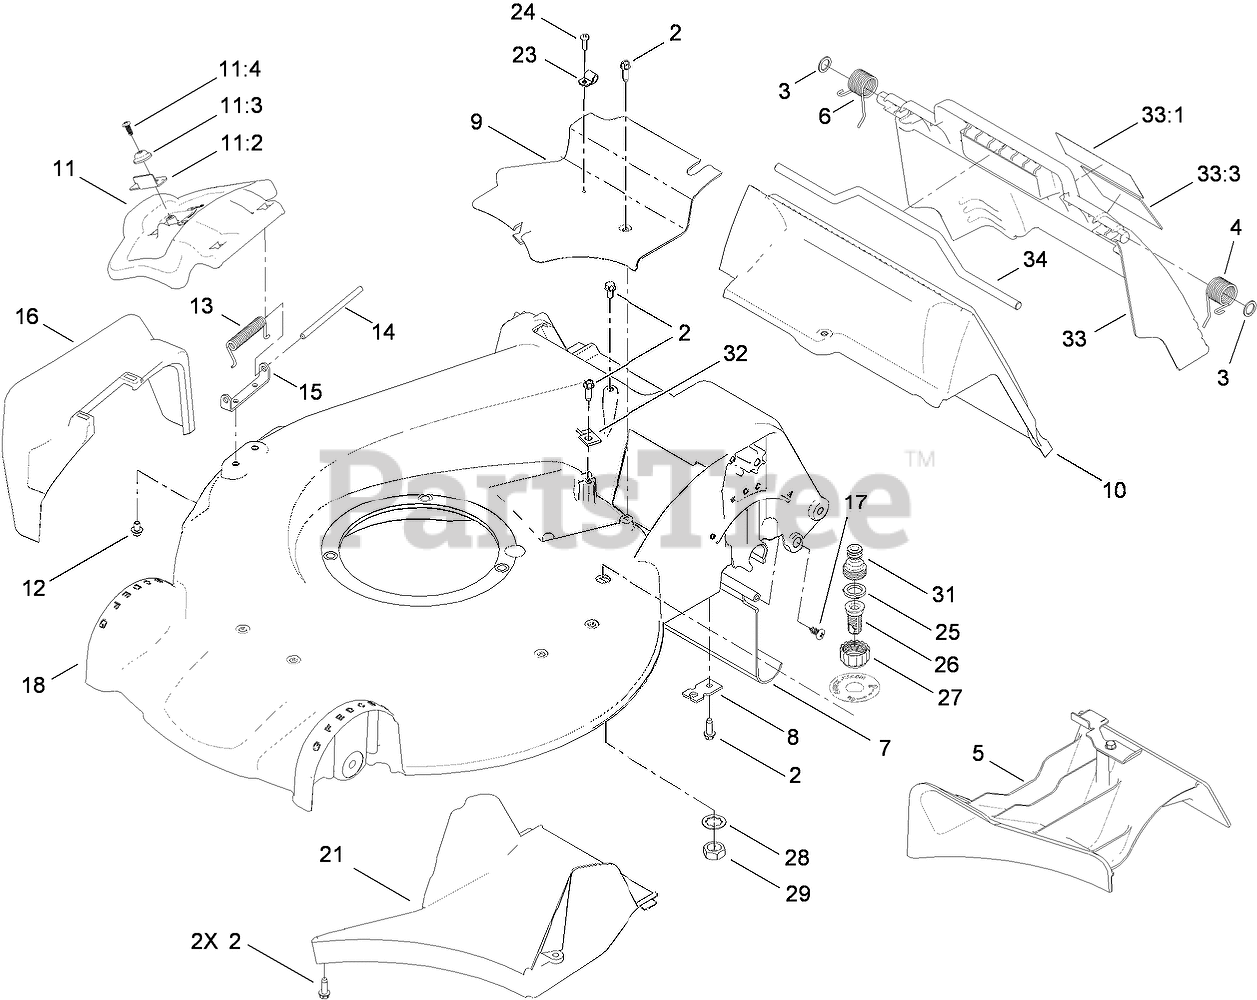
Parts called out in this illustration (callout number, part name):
2	SCREW-HWHTF
3	WASHER-NYLON
4	SPRING-TORSION
5	MULCH PLUG ASM
6	SPRING-TORSION
7	SHIELD-TRAILING
8	BRACKET-CABLE, TRACTION
9	COVER-BELT
11	DISCHARGE DOOR ASM
11:2	LATCH-DOOR
11:3	CAP-DOOR
11:4	SCREW-PLASTITE
12	SCREW-HWH
13	SPRING-TORSION
14	ROD-COVER
15	BRACKET-COVER
16	CHUTE-DISCHARGE, SIDE
17	SCREW-PTH
18	HOUSING ASM
21	TUNNEL-DISCHARGE
23	CLAMP
25	WASHER-SEAL, WASHOUT PORT
26	PORT-WASHOUT
27	COUPLING-HOSE, WASHOUT PORT
28	WASHER-TOOTH, INTERNAL
29	NUT-JAM
31	ADAPTER-CONNECT, QUICK
32	CLAMP-CABLE
33	REAR DOOR ASM
33:1	DECAL-WARNING
33:3	DECAL-WARNING
34	ROD-DEFLECTOR
